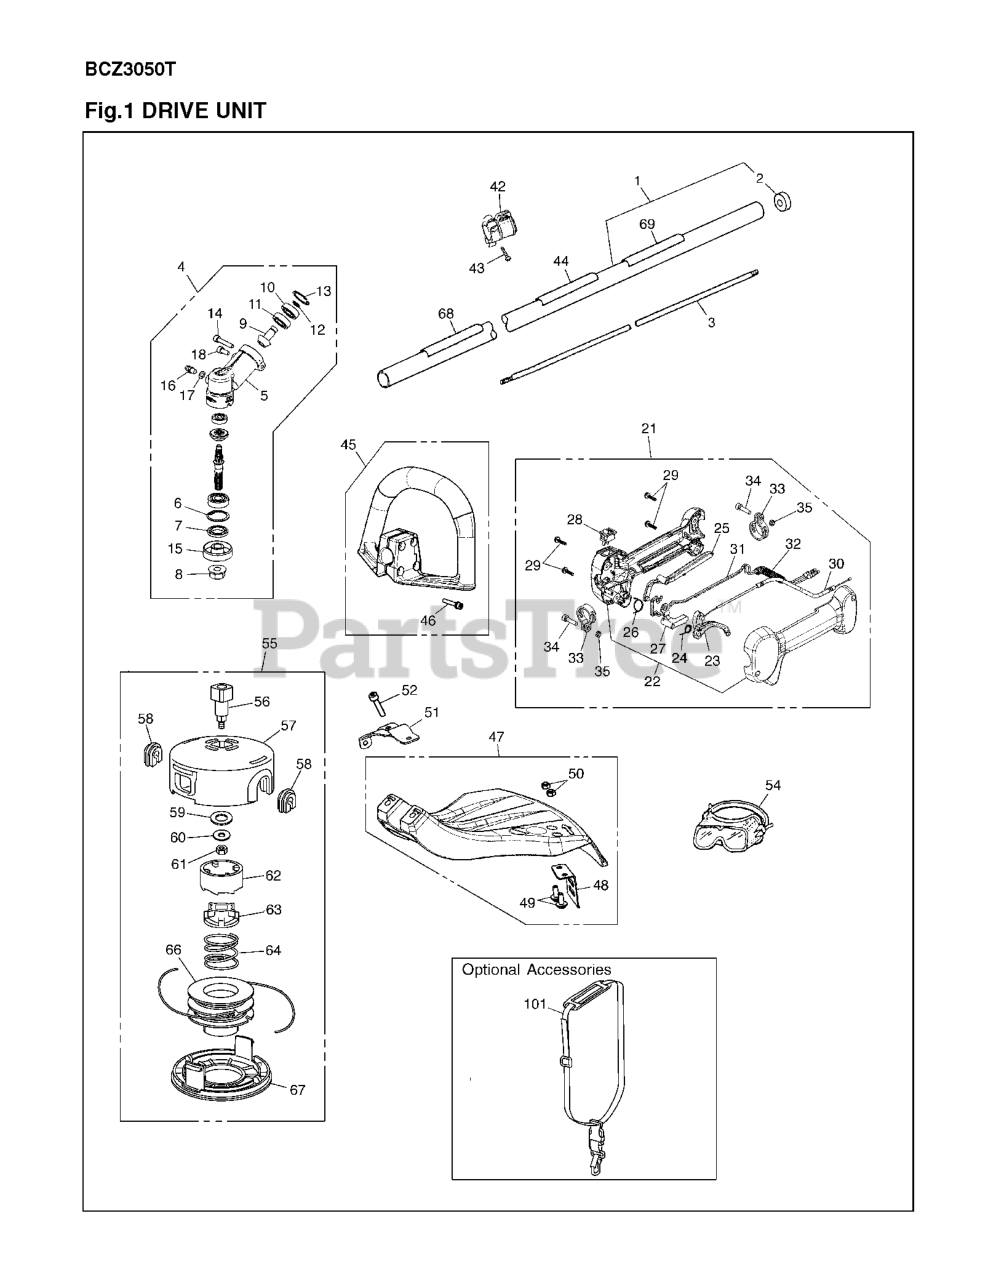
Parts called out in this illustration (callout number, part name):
1	PIPE COMP
3	DRIVESHAFT
4	GEARCASE ASSY
5	GEARCASE
6	RING,SNAP M26x1.2 RP-318013340
14	BOLT TORX
15	HOLDER(A)
18	BOLT, TORX
21	GRIP ASSY
22	GRIP HALF SET
23	LEVER, THROTTLE
24	SPRING, THROTTLE
25	LEVER FOR GRIP (RPLS -0600)
26	SPRING JOINT
27	LEVER JOINT
31	CORD - C
35	NUT
42	HANGER COMP.
44	LABEL CAUTON FOR BC
45	HANDLE ASSY. (RPLS T319514001)
47	GUARD ASSY
52	BOLT, TORX
54	GOGGLExxx (RPLS
55	4" TAP TRIMMER HEAD PT104
56	SHAFT BOLT
57	HOUSING
58	Eyelet Kit, 2-Pack
59	Flat Washer
60	FLAT WASHER
61	Lock Nut
62	CAM FOLLOWER
63	INNER CAM
67	BOTTOM COVER
68	LABEL CAUTON FOR BC
69	CAUTION LAEL
101	STRAP ASSY
